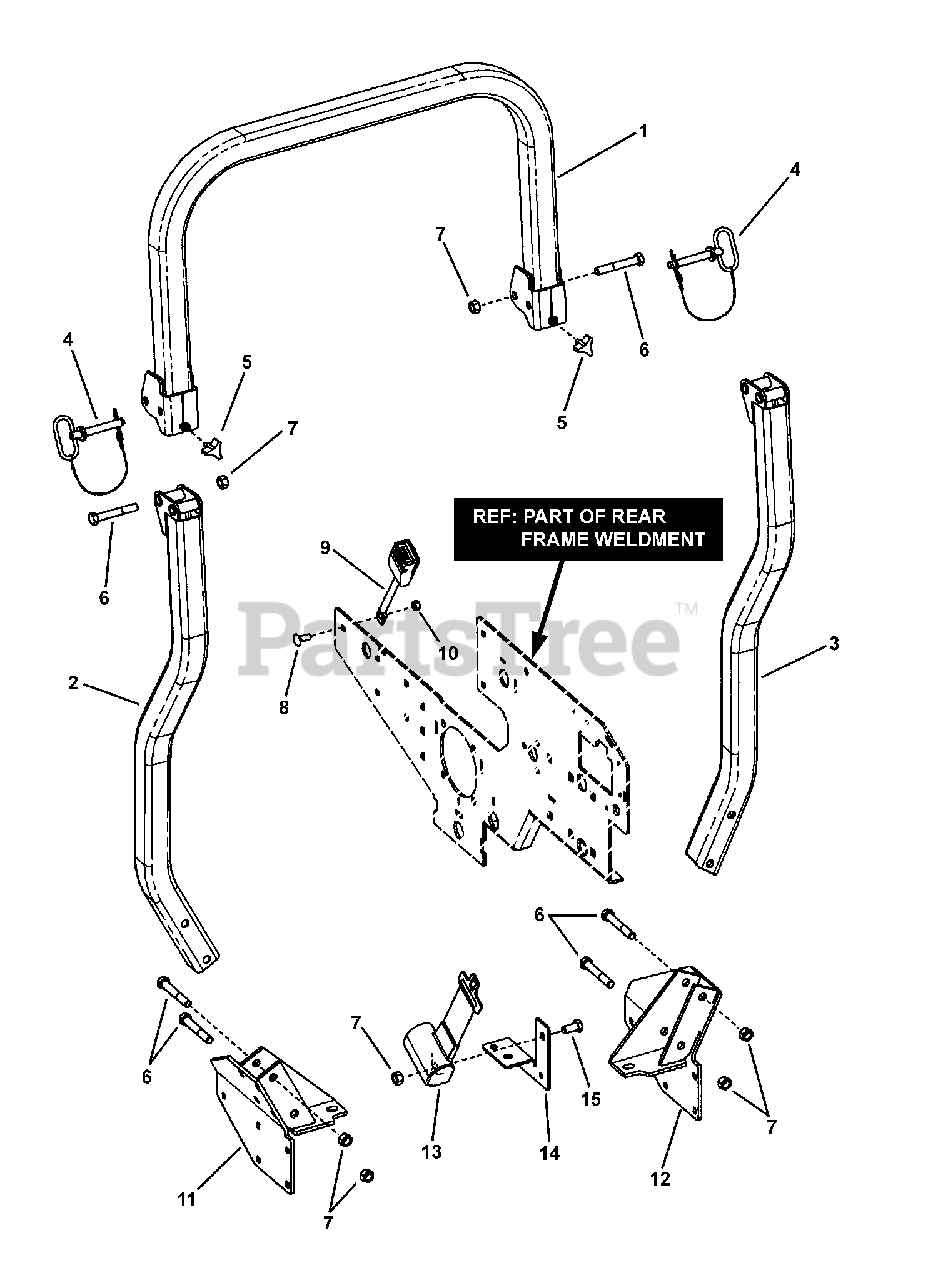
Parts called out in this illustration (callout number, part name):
1	TOP LOOP, Folding
2	WELDMENT POST, RH
3	WELDMENT POST, LH
4	PIN, Hinge (ROPS)
5	STAR KNOB (5/16-18 thread)
6	SCREW, 1/2-13 x 3-1/4" Hex Head Cap, GR 5
7	NUT, 1/2-13 Hex Center Lock, GR 5
8	BOLT, 3/8-16 x 1" Square Neck Carriage, GR 5
9	SEAT BELT, w/Metal Strap
10	NUT, 3/8-16 Hex Center Lock
11	WELDMENT, Right Hand Socket
12	WELDMENT, Left Hand Socket
13	SEAT BELT, Retracter
14	BRACKET, Seat Beal, LH
15	SCREW, 1/2-13 x 1" Hex Head Cap, GR 5
